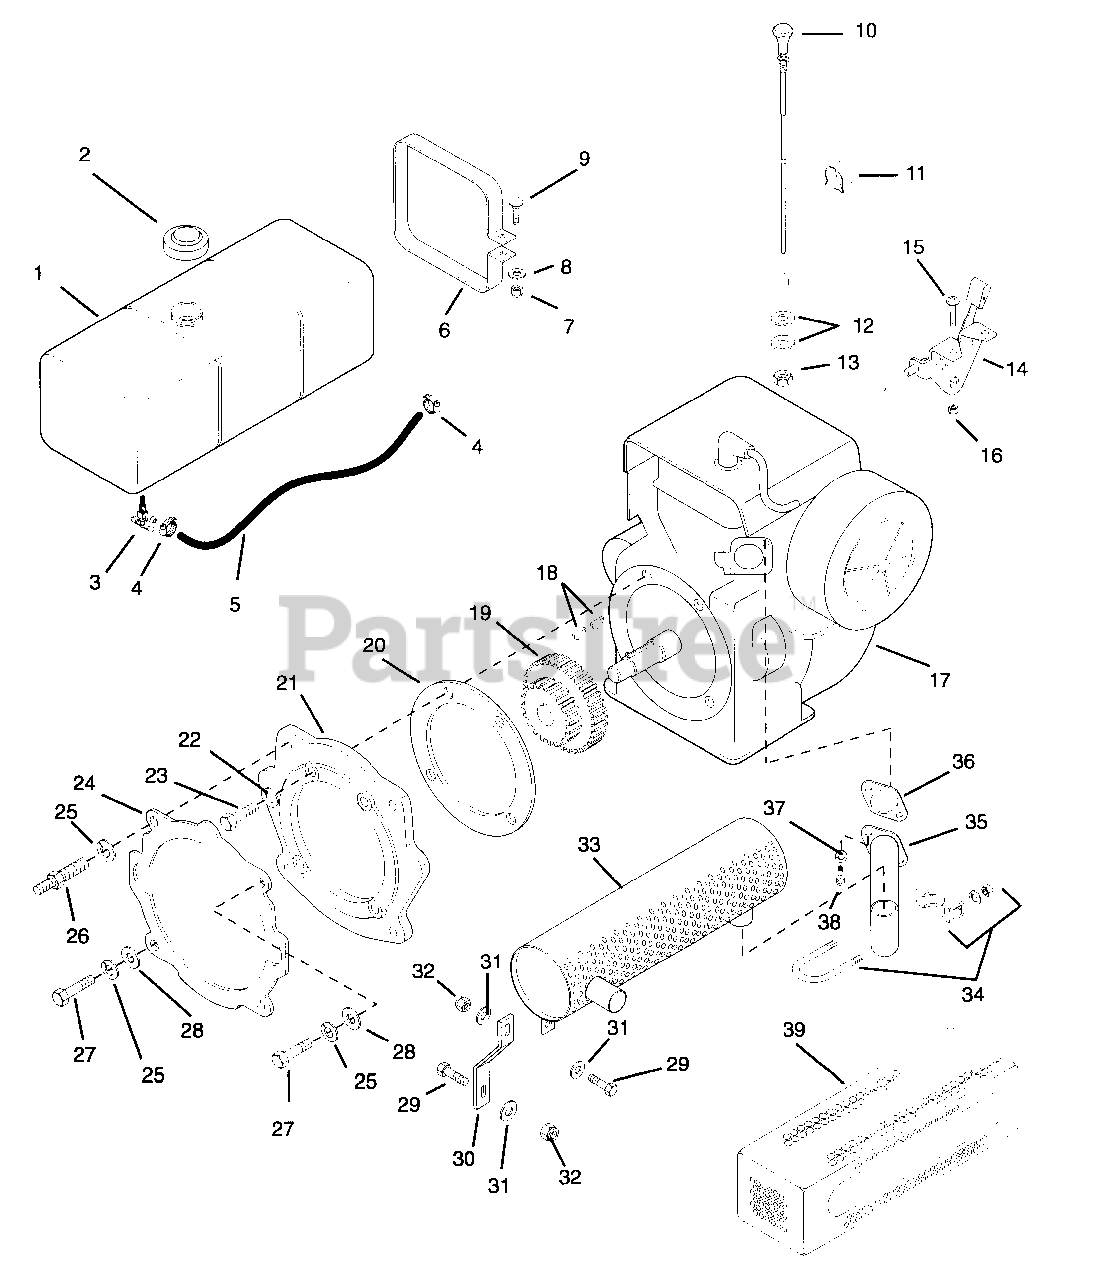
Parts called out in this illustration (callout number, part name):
1	Assembly, Fuel Tank
2	Cap, Gas Tank
3	Valve and Strainer
4	Hose Clamp
5	Gas Line-Bulk
6	Strap, Fuel Tank
7	Nut-Locking-Center .250-20
8	Washer-Flat-Steel .281 x.62 x .065
9	Bolt-Round Head Square Neck .25-20 x 1.75
10	Lever, Choke Control
11	Clamp
12	Washer-Flat-Steel .406 x .812 x .065
13	Nut-Jam .375-24
14	Lever, Throttle Control
15	Screw-Socket Head 10-24 x .50
16	Nut-Locking-Nylon 10-24
17	Engine, 12 HP Elect Magnum
18	Key, Woodruff .16 x .63
19	Gear, 10/12 DP 21/30 Teeth
20	Gasket, Engine to Adapter
21	Adapter, Engine
22	Washer-Lock .375 x .155
23	Bolt-Hex .380-16 x 1.00
24	Gasket, Chassis to Adapter
25	Washer-Lock .438 x .133
26	Stud
27	Bolt-Hex .44-14 x 1.5
28	Washer-Flat-Steel .469 x .938 x .065
29	Bolt-Hex .25-20 x .75 Grade 50
30	Brace, Muffler
31	Washer-Flat-Steel .312 x .734 x .065
32	Nut-Hex .250-20
33	Muffler
34	Clamp-Muffler 1.25
35	Header, Exhaust
36	Gasket, Exhaust
37	Washer-Lock .313 x .078
38	Screw-Cap .31-18 x .75
39	Guard, Muffler
